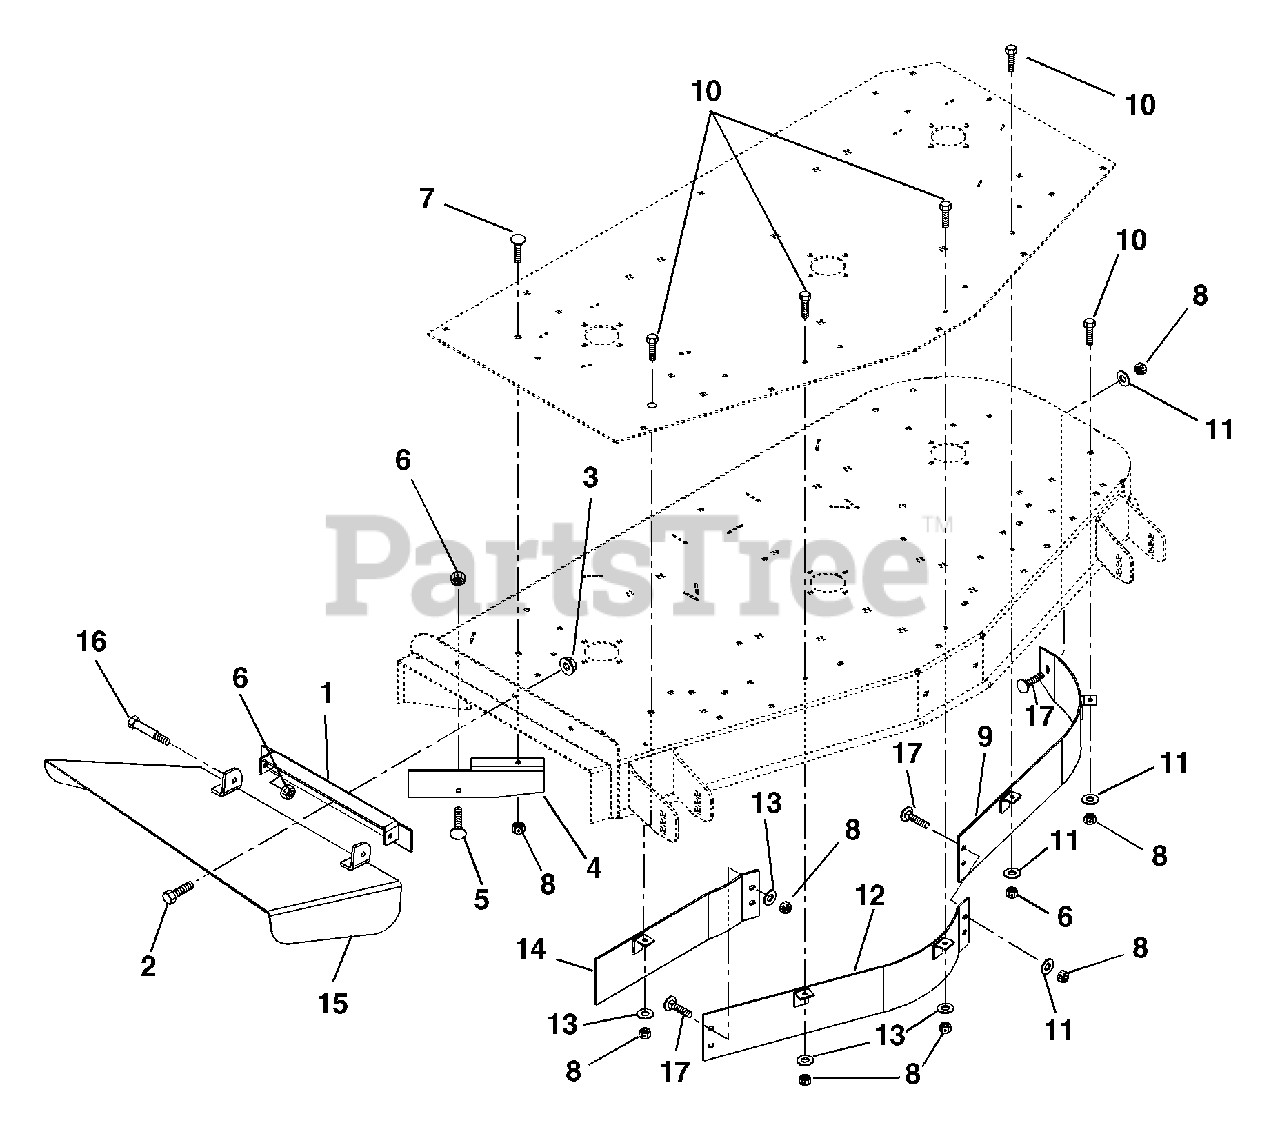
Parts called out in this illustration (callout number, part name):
1	Weldment, Discharge Chute Bracket
2	Bolt-Hex .38-16 x 1.00 Grade 5
3	Nut-Locking-Flange .38-16
4	Deflector, 72"
5	Bolt-Round Head Square Neck .38-16 x 1.00 Grade 2
6	Nut-Locking-Center .38-16
7	Bolt-Round Head Square Neck .31-18 x 1.00 Grade 5
8	Nut-Locking-Nylon .31-18
9	Weldment, 72" Left Hand Baffle
10	Bolt-Hex .31-18 x 1.00 Grade 5
11	Washer-Flat-Steel .312 x .734 x .065
12	Weldment, 72" Center Baffle
13	Washer-Flat-Steel .312 x .734 x .065
14	Weldment, 72" Right Hand Baffle
15	Weldment, Discharge Chute 72"
16	Bolt-Shoulder .38-16 x .38
17	Bolt-Round Head Square Neck .31-18 x .75 Grade 2
18	72" S.D. Mulch Kit
19	72" Discharge Cover Kit
